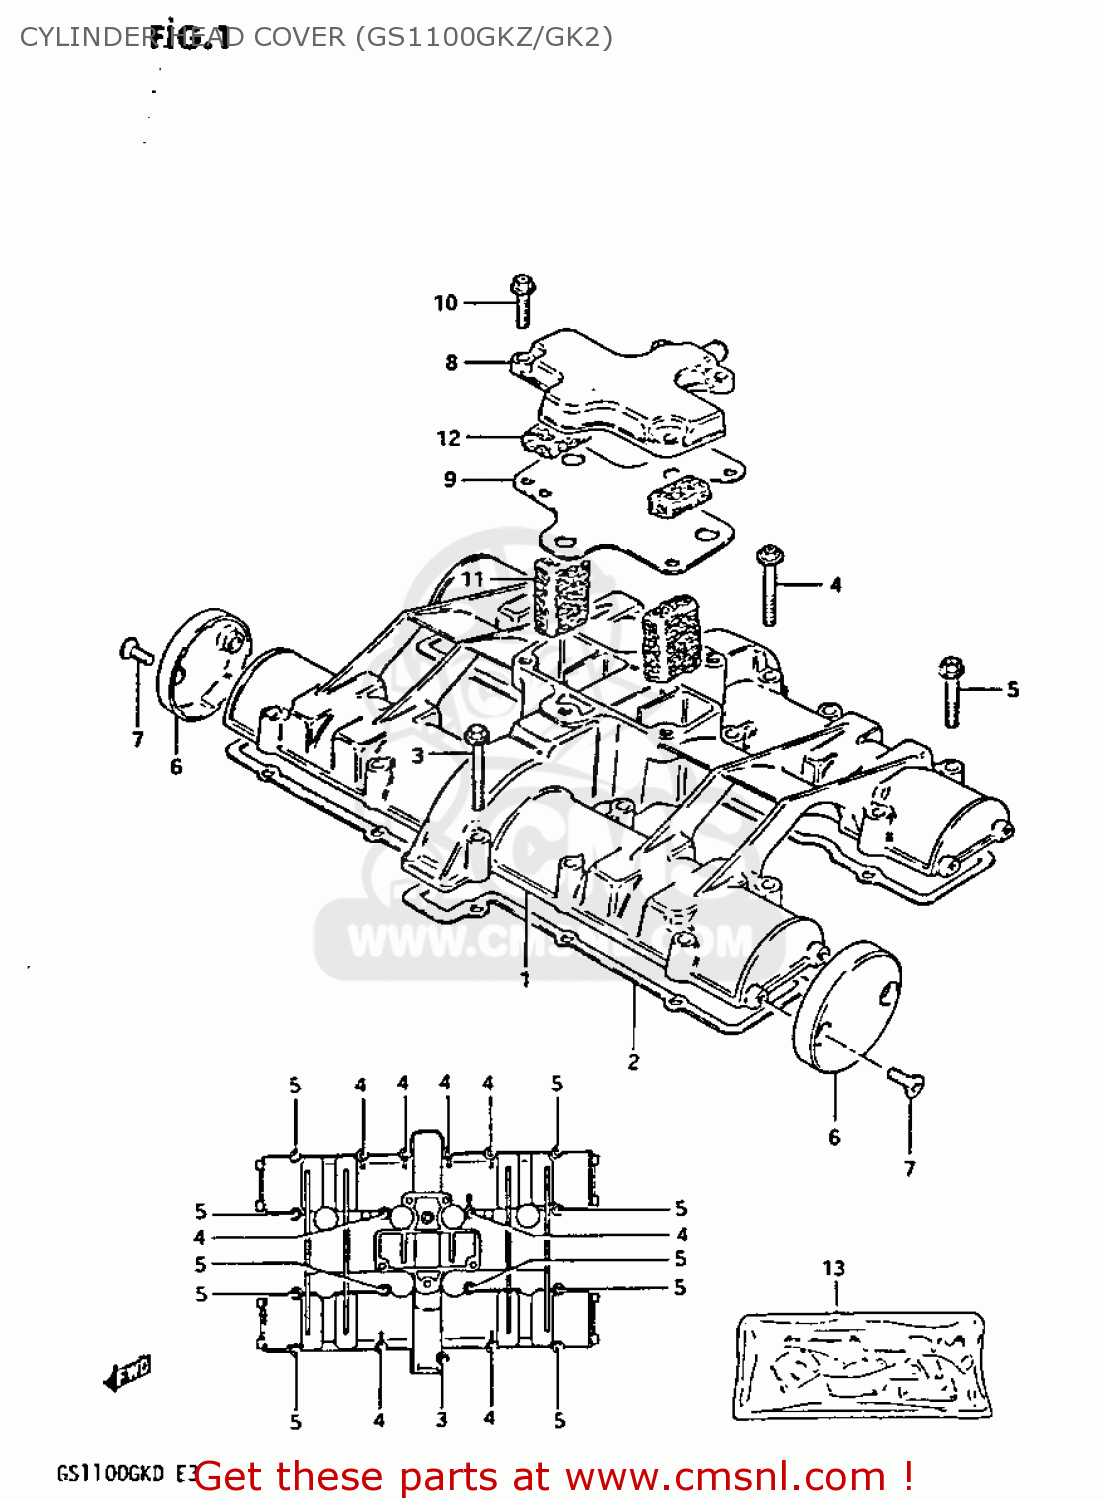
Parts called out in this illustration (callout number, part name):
1	COVER,CYLINDER HEAD
2	GASKET,CYL HEAD COVER (NAS)
3	BOLT,UNDER
4	BOLT
5	BOLT 6X35
6	CAP,CYLINDER HEAD COVER
7	SCREW(5X12)
8	COVER,BREATHER
9	GASKET (MCA)
10	BOLT 6X25
11	COVER,BREATHER
12	SEPARATOR,OIL BREATHER
13	GASKET SET
